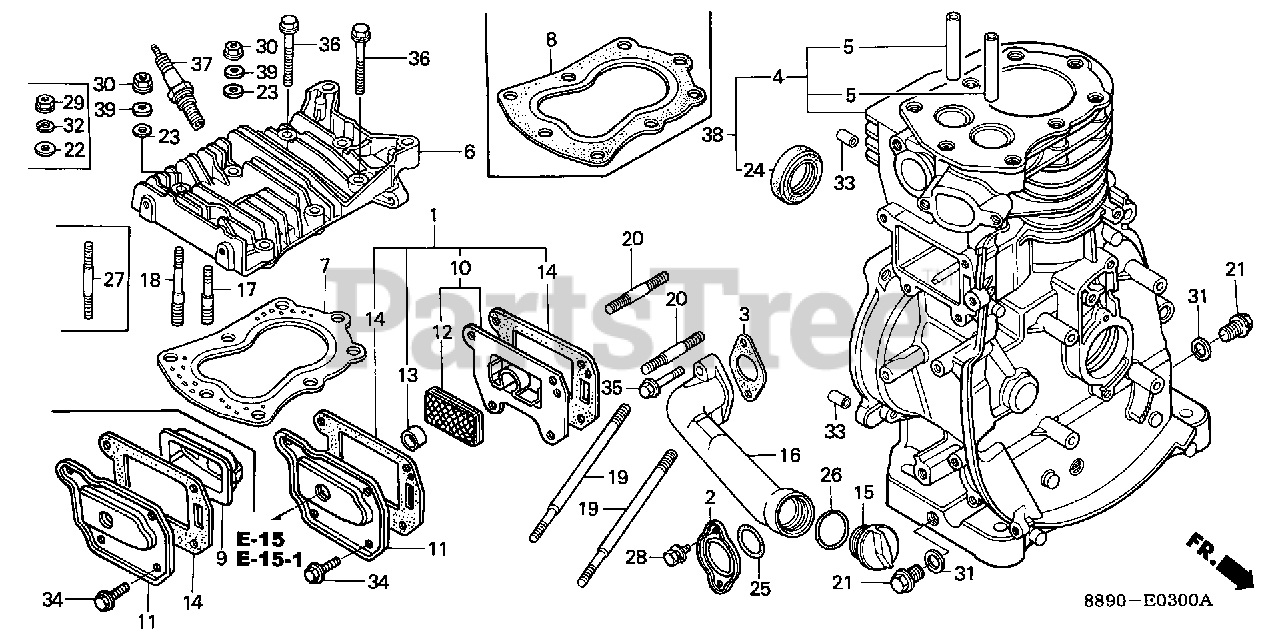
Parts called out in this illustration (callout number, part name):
1	CASE KIT, BREATHER (NOT AVAILABLE)
2	COVER, OIL PAN HOLE
3	GASKET, OIL PAN HOLE COVER (NOT AVAILABLE)
4	CYLINDER (CRANKSHAFT P.T.O.)
4	CYLINDER
5	GUIDE, VALVE
6	CYLINDER HEAD
6	CYLINDER HEAD (NOT AVAILABLE)
8	GASKET, CYLINDER HEAD
9	CASE, BREATHER
10	CASE, BREATHER
11	COVER, TAPPET ROOM
12	FILTER, BREATHER
13	SEAL, BREATHER
14	GASKET, TAPPET COVER
15	CAP, OIL (YELLOW)
16	PIPE, OIL
17	BOLT, STUD (M8XM10X63)
18	BOLT, STUD (M8XM10X81)
19	BOLT, STUD (8X110)
19	BOLT, STUD (8X104)
20	BOLT, STUD (8X35)
21	BOLT, DRAIN PLUG (12X15)
22	WASHER, HEAD (8MM)
23	WASHER (23X8.3X3.2)
24	OIL SEAL (25X41X6)
25	O-RING (27X2.0)
26	O-RING (26X2.7)
27	BOLT, STUD (8X65)
27	BOLT, STUD (8X80) (NOT AVAILABLE)
28	BOLT-WASHER (6X12)
29	NUT, FLANGE (8MM)
30	NUT-WASHER (8MM)
31	WASHER, DRAIN PLUG (12MM)
32	WASHER, SPRING (8MM)
33	PIN, DOWEL (8X14)
34	BOLT, FLANGE (6X12)
35	BOLT, FLANGE (6X25)
36	BOLT, FLANGE (8X50) (NOT AVAILABLE)
37	SPARK PLUG (B-4H) (NGK)
37	SPARK PLUG (BR-4HS) (NGK)
37	SPARK PLUG (W14F-U) (DENSO)
37	SPARK PLUG (W14FR-U)
37	SPARK PLUG (BPR4HS-10)
37	SPARK PLUG (BP4HS-10)
37	SPARK PLUG (W14FP-UL10) (DENSO)
37	SPARK PLUG (W14FPR-UL10) (DENSO)
37	SPARK PLUG (W20FS-U) (DENSO)
37	SPARK PLUG (W20FPR-U10) (DENSO)
